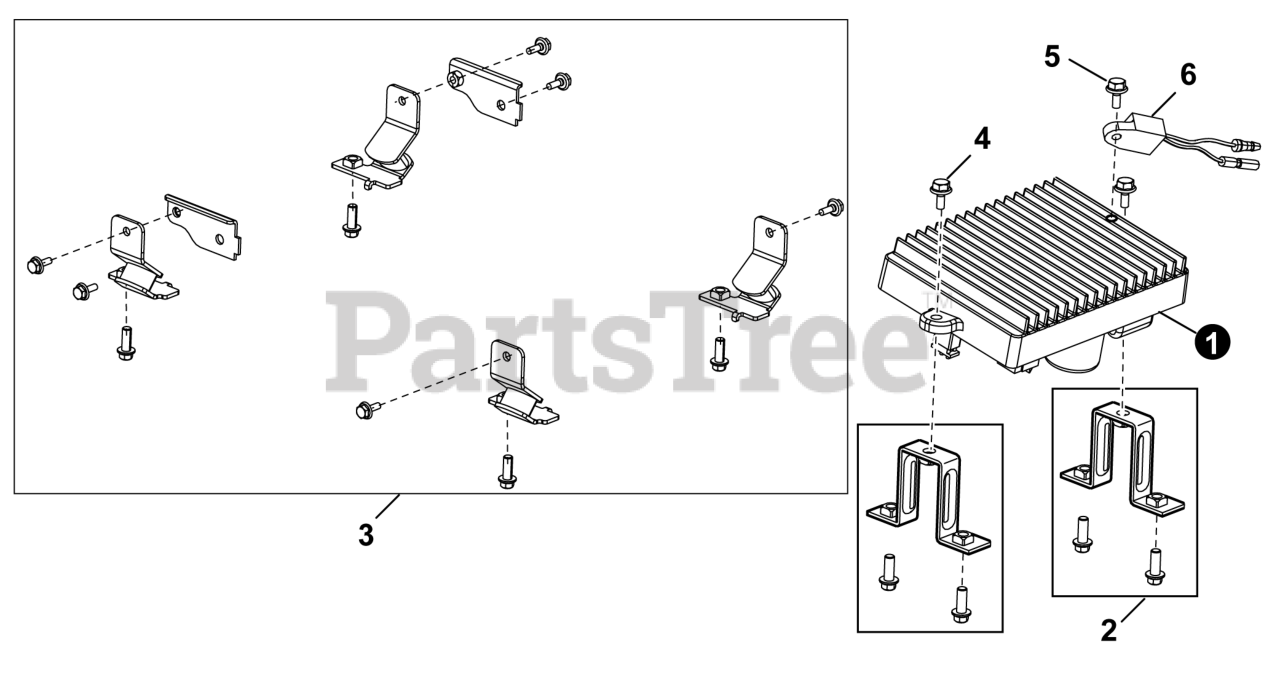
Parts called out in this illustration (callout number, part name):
1	INVERTOR
2	FRAME, INVERTER
3	KIT, ENGINE SUPPORT
6	PROTECTOR, OIL
